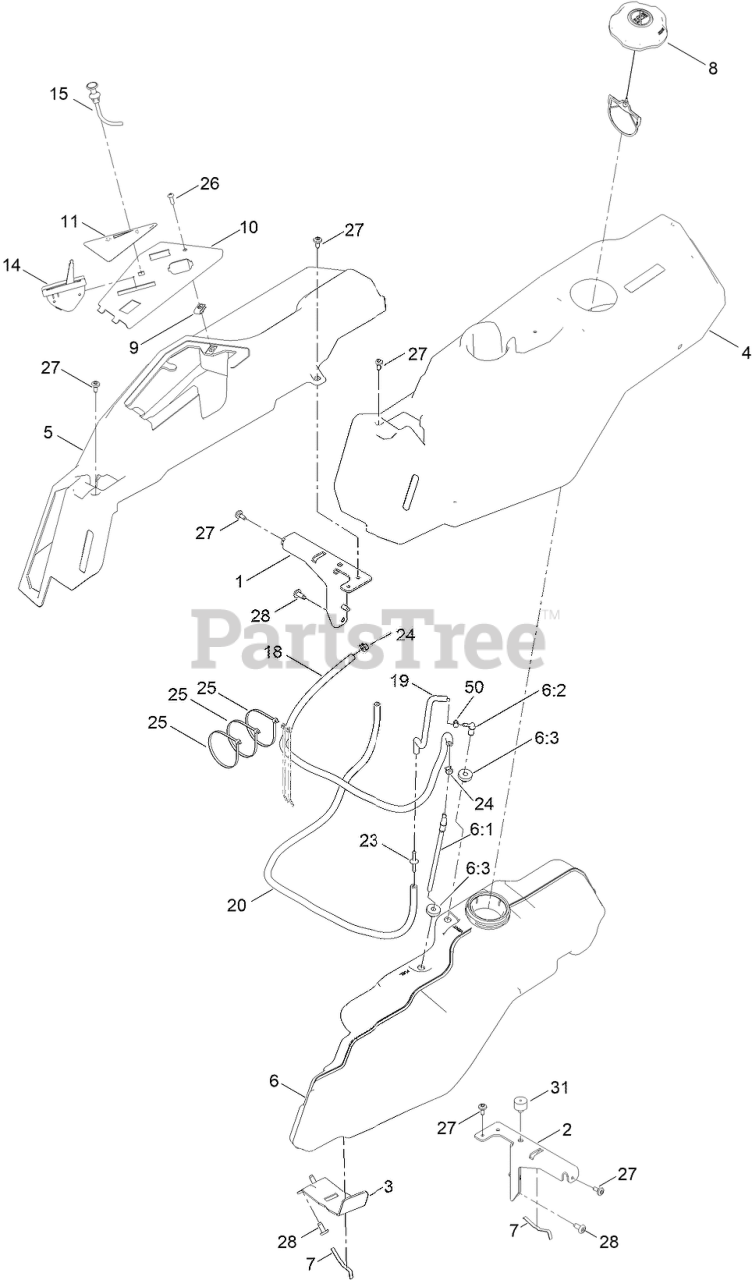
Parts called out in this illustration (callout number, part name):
1	SUPPORT-POD, RH
2	SUPPORT-POD, LH
3	SUPPORT-TANK, FUEL
4	POD-LH
5	POD-RH
6	TANK-FUEL ASM
6:1	CONNECTOR-ELBOW, 90 DEG
6:2	FITTING-ELBOW 90
6:3	BUSHING
7	SPRING
8	CAP-FUEL, RATCHETING
10	PANEL - CONTROL
11	DECAL-PANEL, CONTROL
14	CABLE-THROTTLE
15	CABLE-CHOKE
18	HOSE-FUEL
19	HOSE-FUEL
23	ADAPTER ORIFICE
24	CLAMP-HOSE
25	TIE-CABLE
26	SCREW-PRH
27	SCREW-SHOULDER
31	BUMPER-GROMMET
50	CLAMP-HOSE
